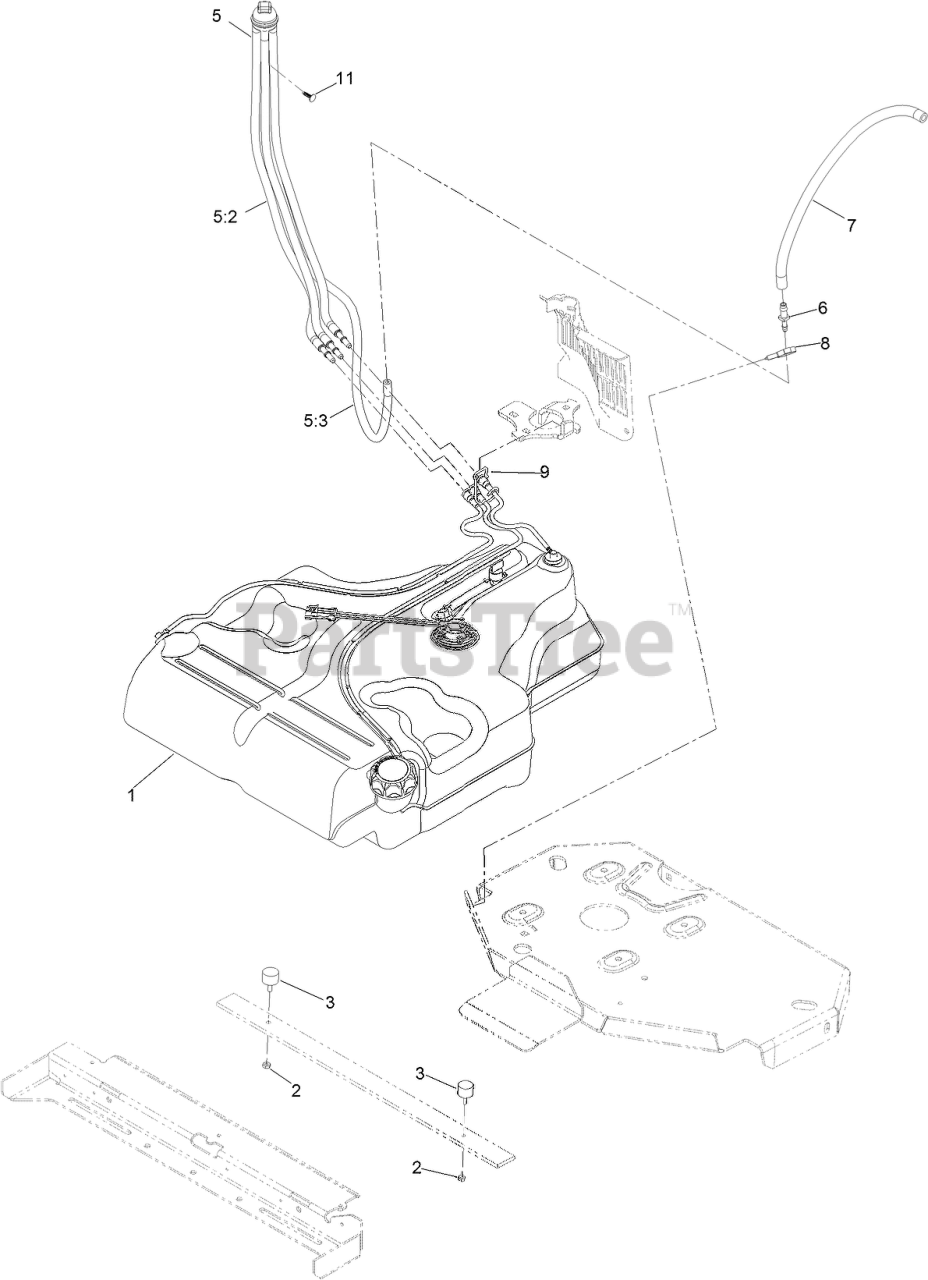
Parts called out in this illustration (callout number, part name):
1	FUEL TANK ASM
2	NUT-JAM
5	FUEL MANIFOLD VENT ASM
5:2	HOSE-FUEL
5:3	HOSE-FUEL
6	FITTING-STRAIGHT
7	HOSE-FUEL
8	CLAMP-HOSE
9	RETAINER-LINE, VAPOR
11	PLUG-PLASTIC
